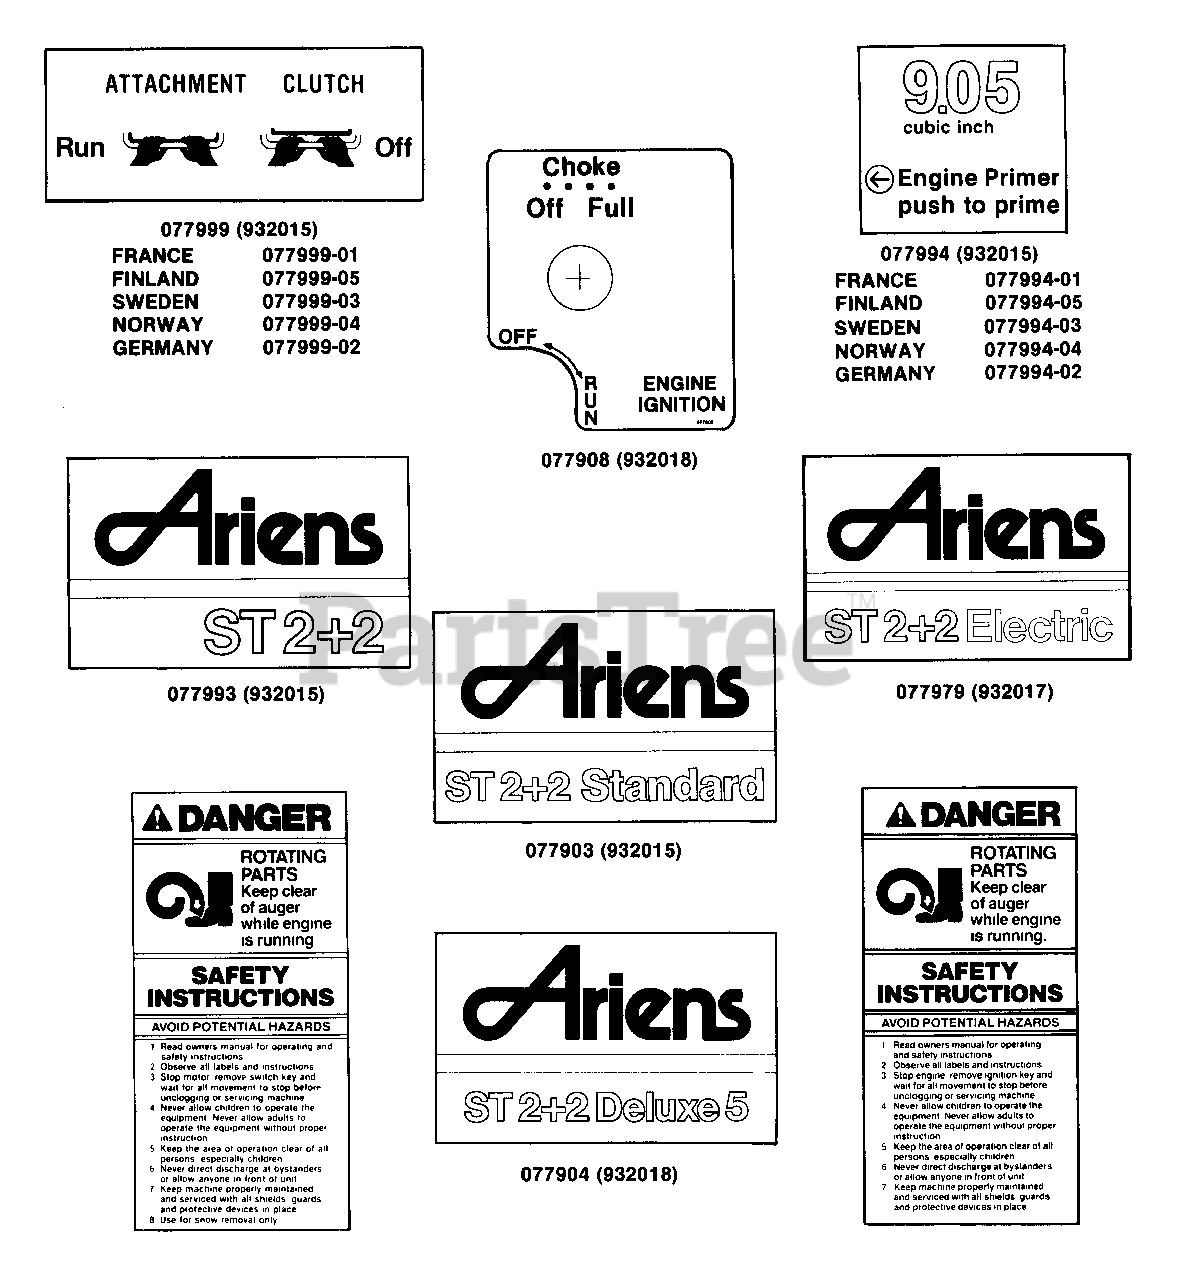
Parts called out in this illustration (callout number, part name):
1	DECAL-ST2+2 STANDARD
2	DECAL-ST2+2 DELUXE 5
3	DECAL-CHOKE & SWITCH
4	DECAL ST2+2 ELECTRIC
5	DECAL ARIENS ST2+2
6	ENGINE DECAL
7	HANDLEBAR DECAL
8	DECAL - DANGER
9	DECAL - DANGER
